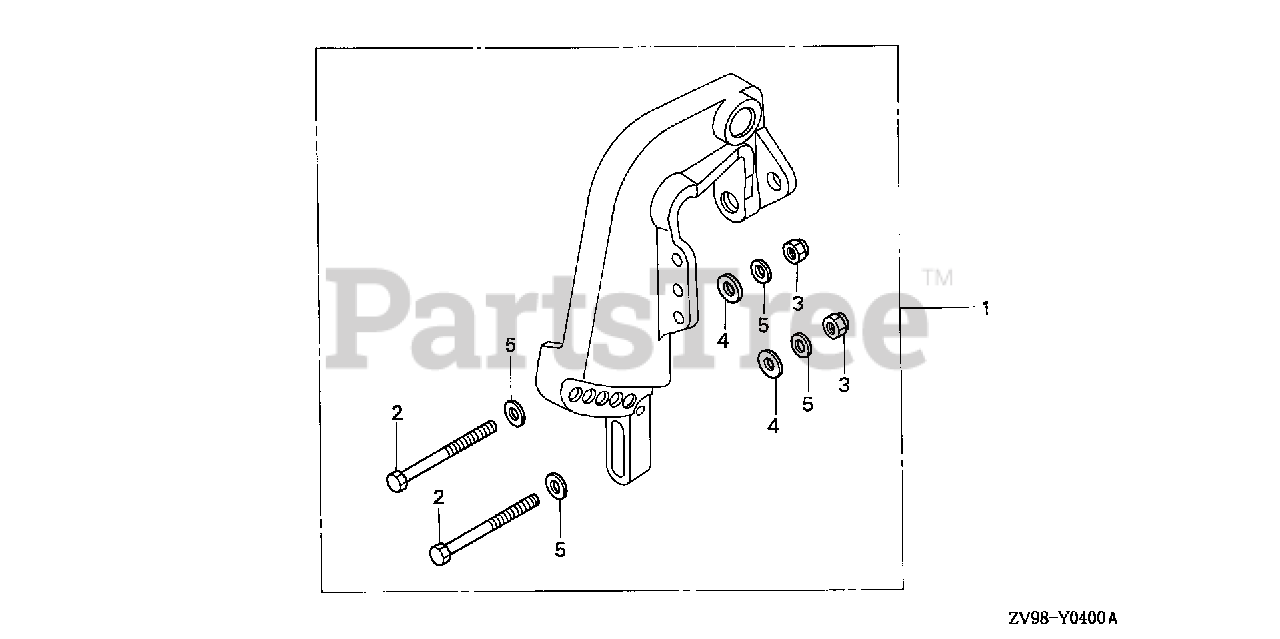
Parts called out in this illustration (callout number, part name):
1	INSTALLATION KIT, OUTBOARD
2	BOLT, HEX. (10X100)
3	NUT, SELF-LOCK (10MM)
4	WASHER, PLAIN (10MM)
5	WASHER, PLAIN (10MM)
